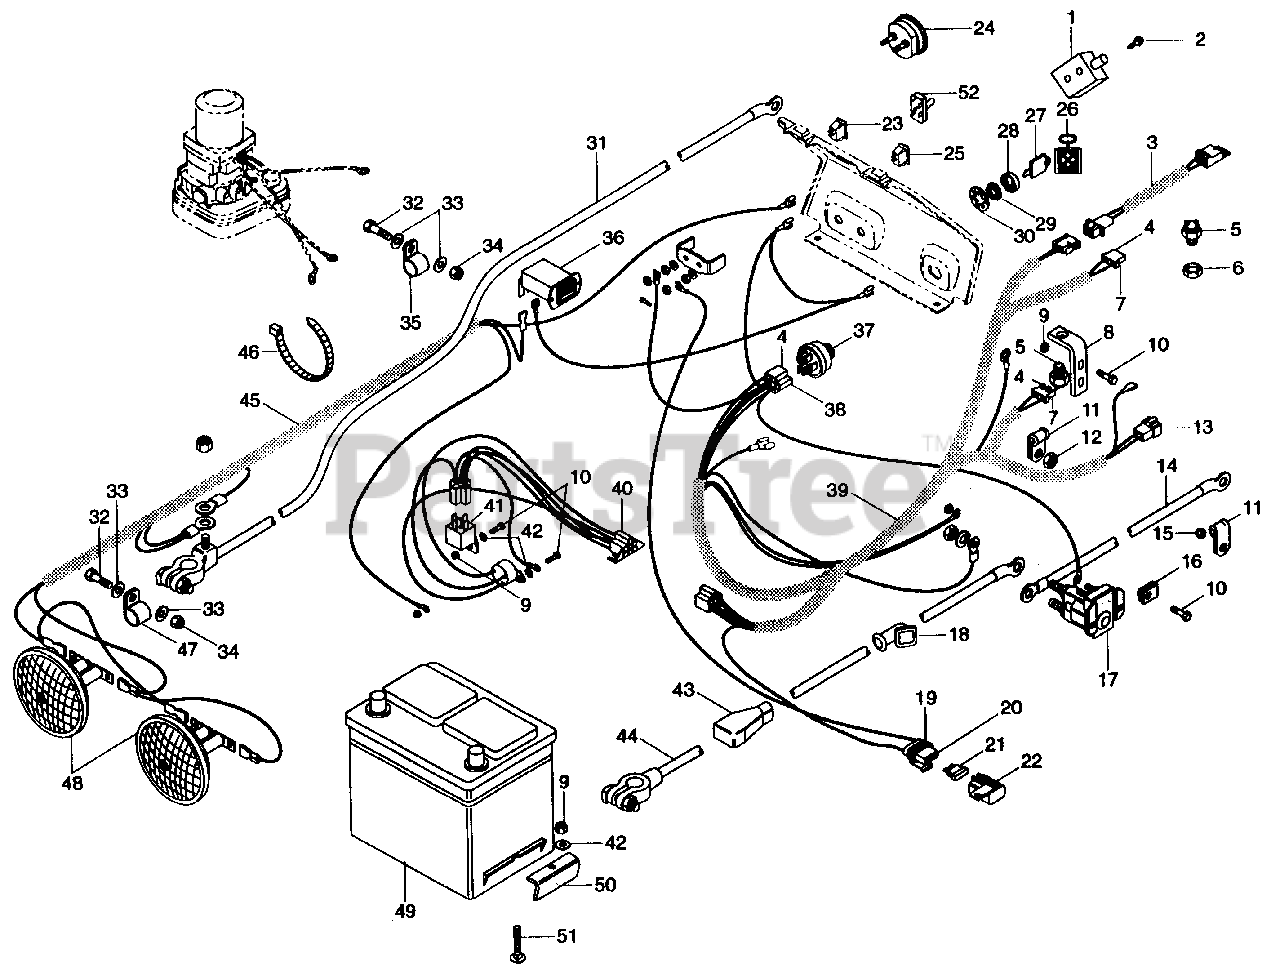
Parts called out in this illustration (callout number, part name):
1	SWITCH, DOUBLE POLE N.O./N.O.
2	SCR. TAP 12-24 X .50 HWH PL
3	HARNESS, WIRING SEAT SWITCH
4	TERMINAL
5	SWITCH-NEUTRAL START N.O.
6	NUT-STAMPED .56-18
7	CONN, 2 WIRE SWITCH
8	BRKT, SWITCH
9	NUT-LK-NYL .250-20 PL
10	BLT-HEX .25-20 X .75 PL GR 5
11	CLAMP
12	NUT-LK-CTR .375-16 TYP N
13	CONNECTOR
14	CABLE STARTER
15	NUT-LK-NYL .375-16 PL
16	NUT-SPEED .25-20
17	SOLENOID
18	BOOT, INSULATOR
19	ASM, CONN WEATHER TIGHT
20	TERM., FOR 14-16 GA WIRE
21	FUSE, 25 AMP
22	COVER
23	LIGHT, INDICATOR
24	GAUGE-AMMETER
25	SWITCH, LIGHT
26	KEY CHAIN
27	IGNITION SWITCH KEY
28	CAP-IGNITION SWITCH
29	NUT-PANEL .562-24 GRECO
30	WSHR-LOCK INT .563 X .040 PL
31	CBL, NEGATIVE BATTERY
32	BLT-HEX .31-18 X 1.00 PL GR 5
33	WSHR-FL-STL .344 X .688 X .065 PL
34	NUT-LK-NYL .312-18 PL
35	CLAMP, STEEL 1.0
36	HOUR METER
37	IGNITION SWITCH
38	CONNECTOR
39	HARNESS, WIRING
40	MODULE, TIME DELAY
41	RELAY
42	WSHR-FL-STL .281 X .62 X .065 PL
43	CVR, BATTERY TERMINAL
44	CABLE, BAT TO MAG SWITCH
45	HARNESS, WIRING GRND & LIGHTS
46	TIE CABLE
47	CABLE CLAMP
48	HEADLIGHT
49	BATTERY, 12V 22F 30 GT
50	CLAMP
51	BLT-RDHDSQNK .25-20 X 1.75
52	SWITCH ASSEMBLY
